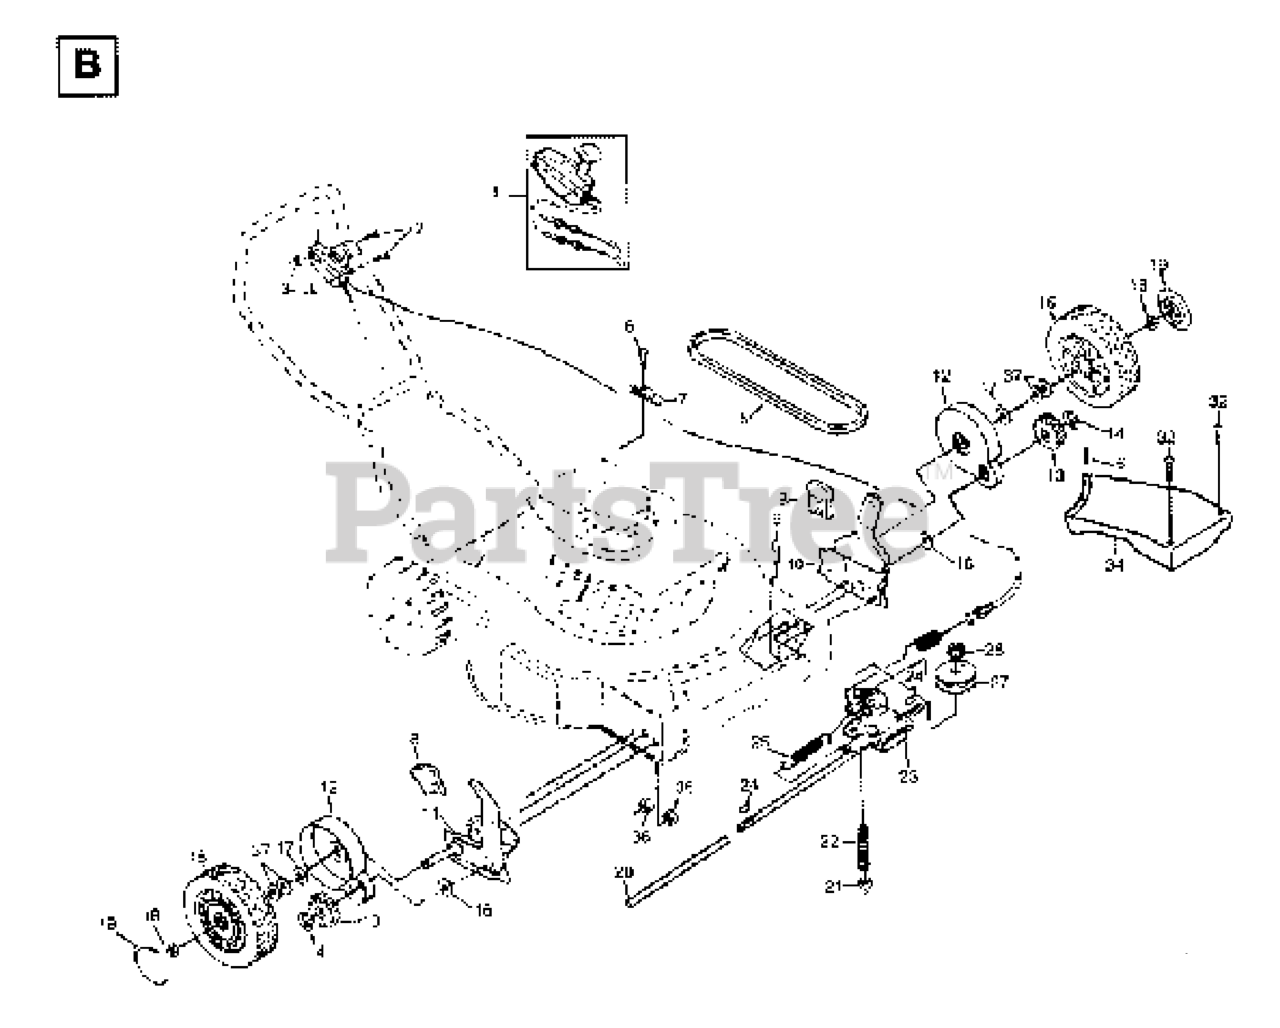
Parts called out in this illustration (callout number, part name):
1	DRIVE CONTROL
2	SCREW 1/4-20 X 2.12
3	NUT
5	BELT DRIVE
6	TAPPING SCREW
7	GUIDE CLIP PM
8	SELECTOR KNOB
10	BRACKET-LH
11	BRACKET
12	DUST SHROUD PM
13	PINION GEAR
14	E-RING 7/16 RE
15	WHEEL AND TIRE ASSY
17	WASHER FLUT
18	HEX FLANGE LOCKNT
20	DRV SHAFT TUBE PM
21	NUT
22	SPRING.EXTENSION
23	RP.GEAR HOUSING
24	HI PRO KEY
27	FLANGED LOCKNUT 3/8-16 ZINC
28	FLANGED LOCKNUT 3/8-16 ZINC
34	COVER DRIVE
36	NUT
37	WAVE WASHER
